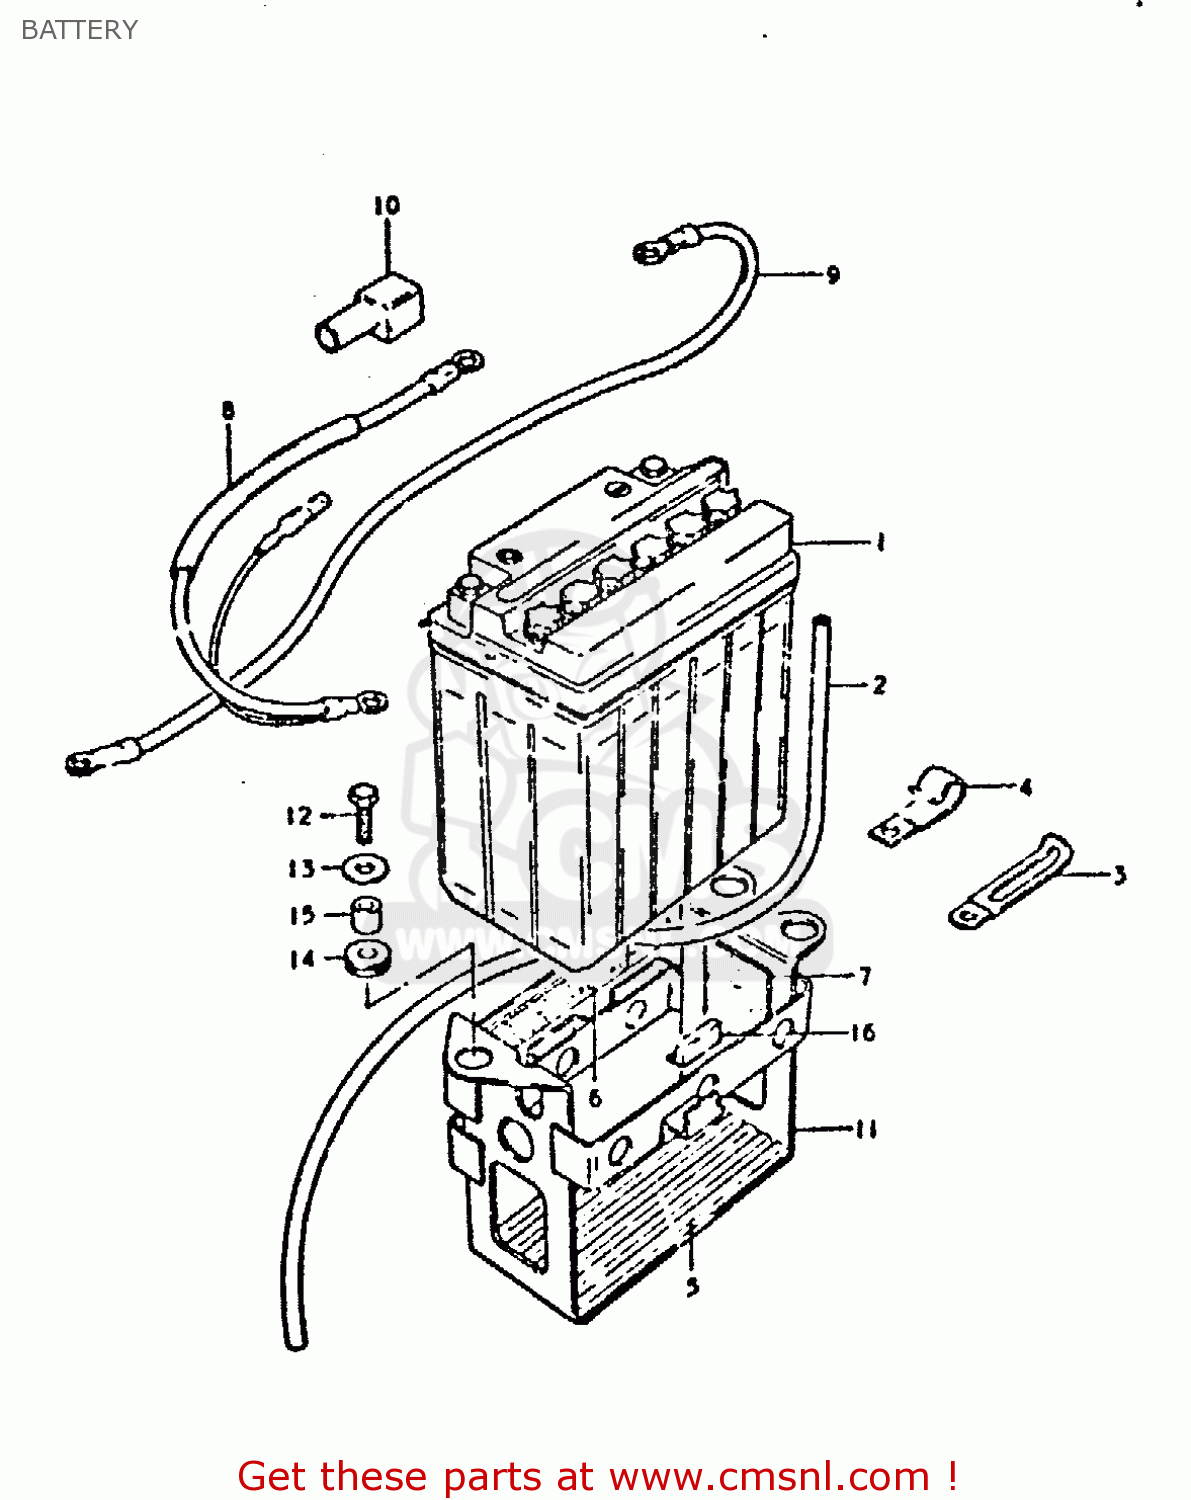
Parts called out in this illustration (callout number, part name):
1	BATTERY ASSY (12V)
2	HOSE,BATTERY EXHAUST
3	CLAMP L:35
4	CLAMP
5	PROTECTOR,BATTERY
6	PROTECTOR(20X90)X4
7	PROTECTOR,BATTERY
8	WIRE,BATTERY PLUS
9	LEAD WIRE,BATTERY(-)
10	CAP,TERMINAL
11	HOLDER,BATTERY
12	BOLT, UPPER
13	WASHER
14	CUSHION
15	SPACER(6.1X9X7.5)
16	CUSHION,FRAME COVER
